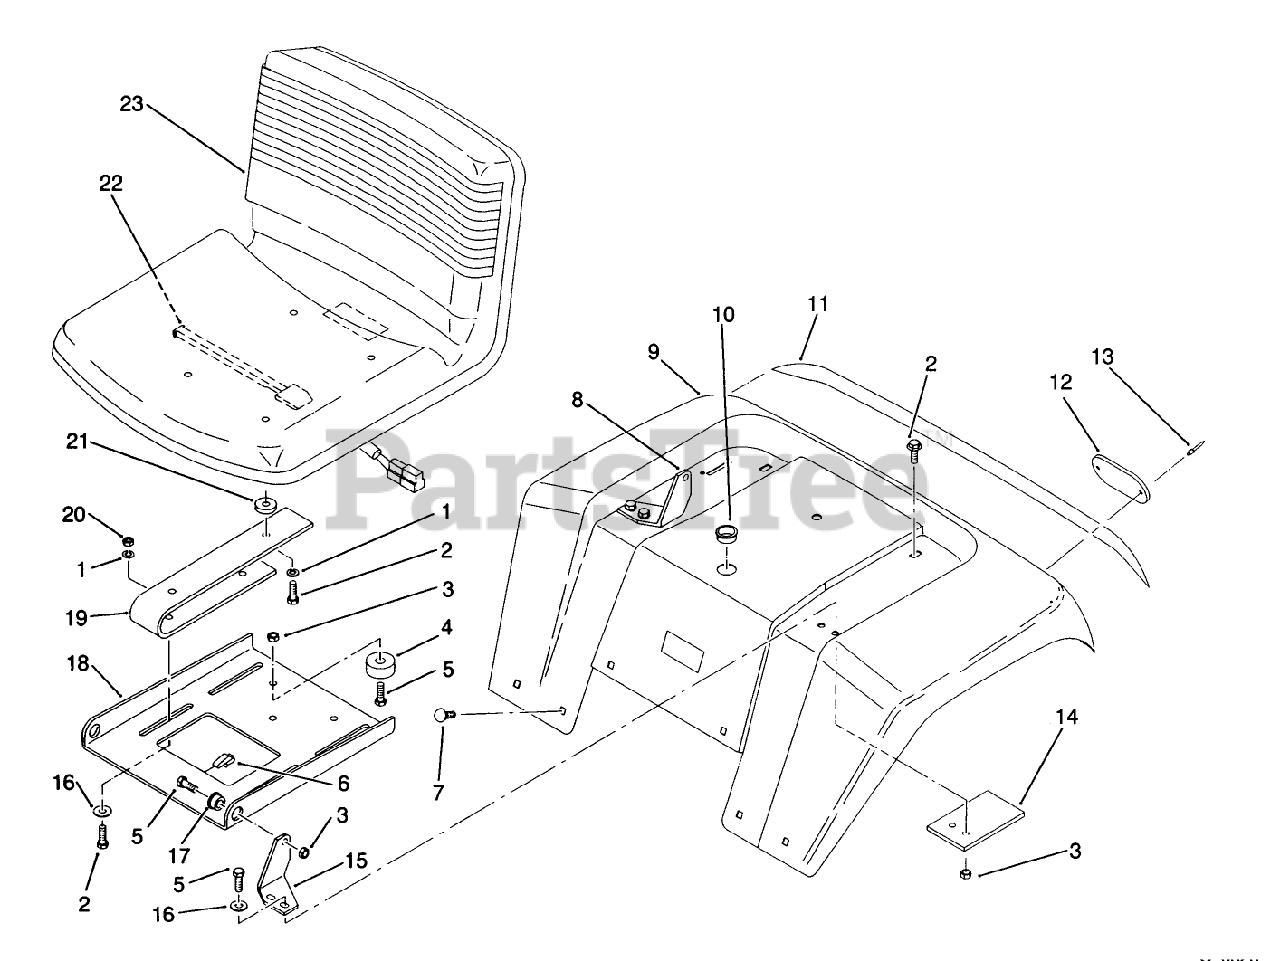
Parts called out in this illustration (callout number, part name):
4	BUMPER
6	J-CLIP
8	BRACKET-PIVOT R.H *B (NS)
9	FENDER *R
10	BUSHING-NYLON 1.093
11	DECAL-FENDER
15	BRACKET-PIVOT L.H *B
17	BUSHING
21	SPACER-NYLON
22	SWITCH-SEAT
